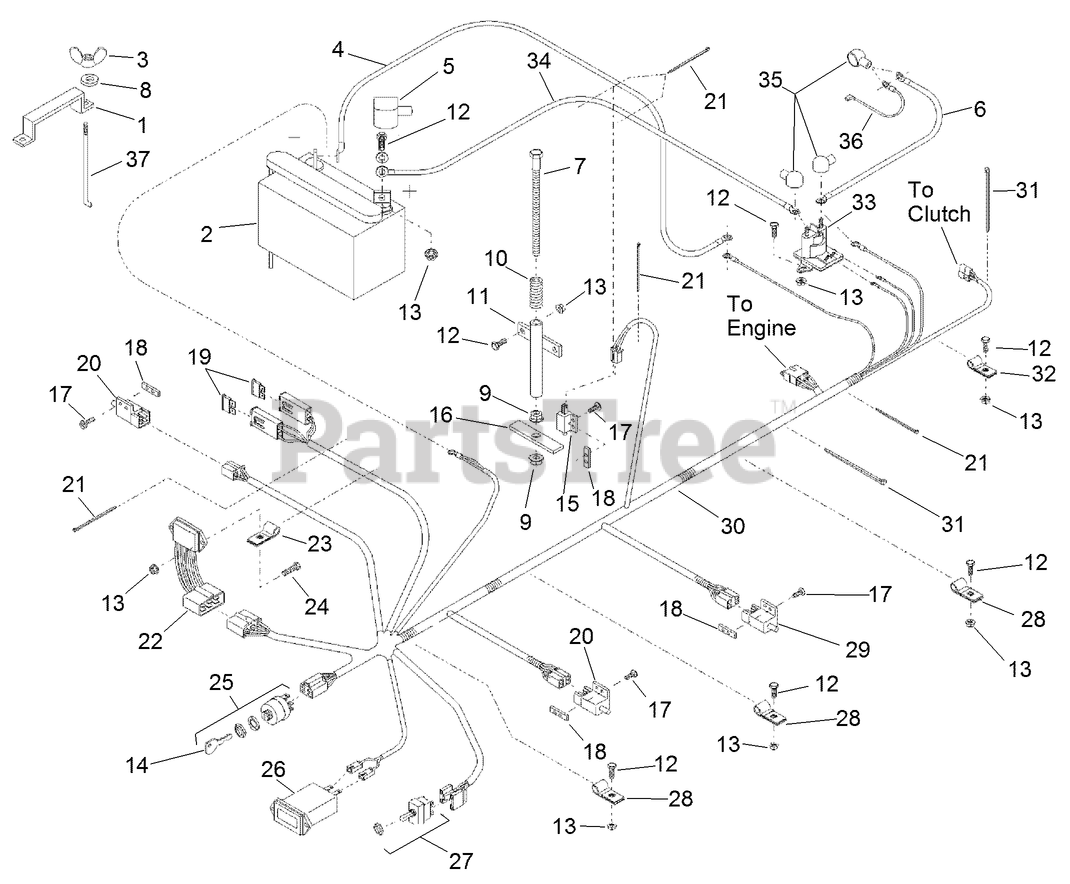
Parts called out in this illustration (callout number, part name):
1	Strap-Hold Down
2	Battery
3	Wingnut
4	Wire-Ground
5	Insulator Battery
6	Wire-Starter
7	Screw
8	WASHER-FLAT
9	NUT-HF
10	Spring
11	Mount-Spring
12	SCREW-HH
13	NUT-HF
14	KEY-IGNITION
15	Switch-Seat
16	Actuator-Switch
17	Screw
18	Plate
19	Fuse
20	Switch-Drive Lever
21	Tie-Plastic
22	Module-Safety
23	Clip
24	SCREW-HH
25	Ignition Switch
26	Meter-Hour
27	Switch
28	Clip
29	Switch-Brake
30	Harness-Wire
31	Tie-Plastic
32	Clip
33	Switch-Solenoid
34	Wire
35	Insulator Solenoid
36	Wire-Starter Solonoi
37	Bolt
